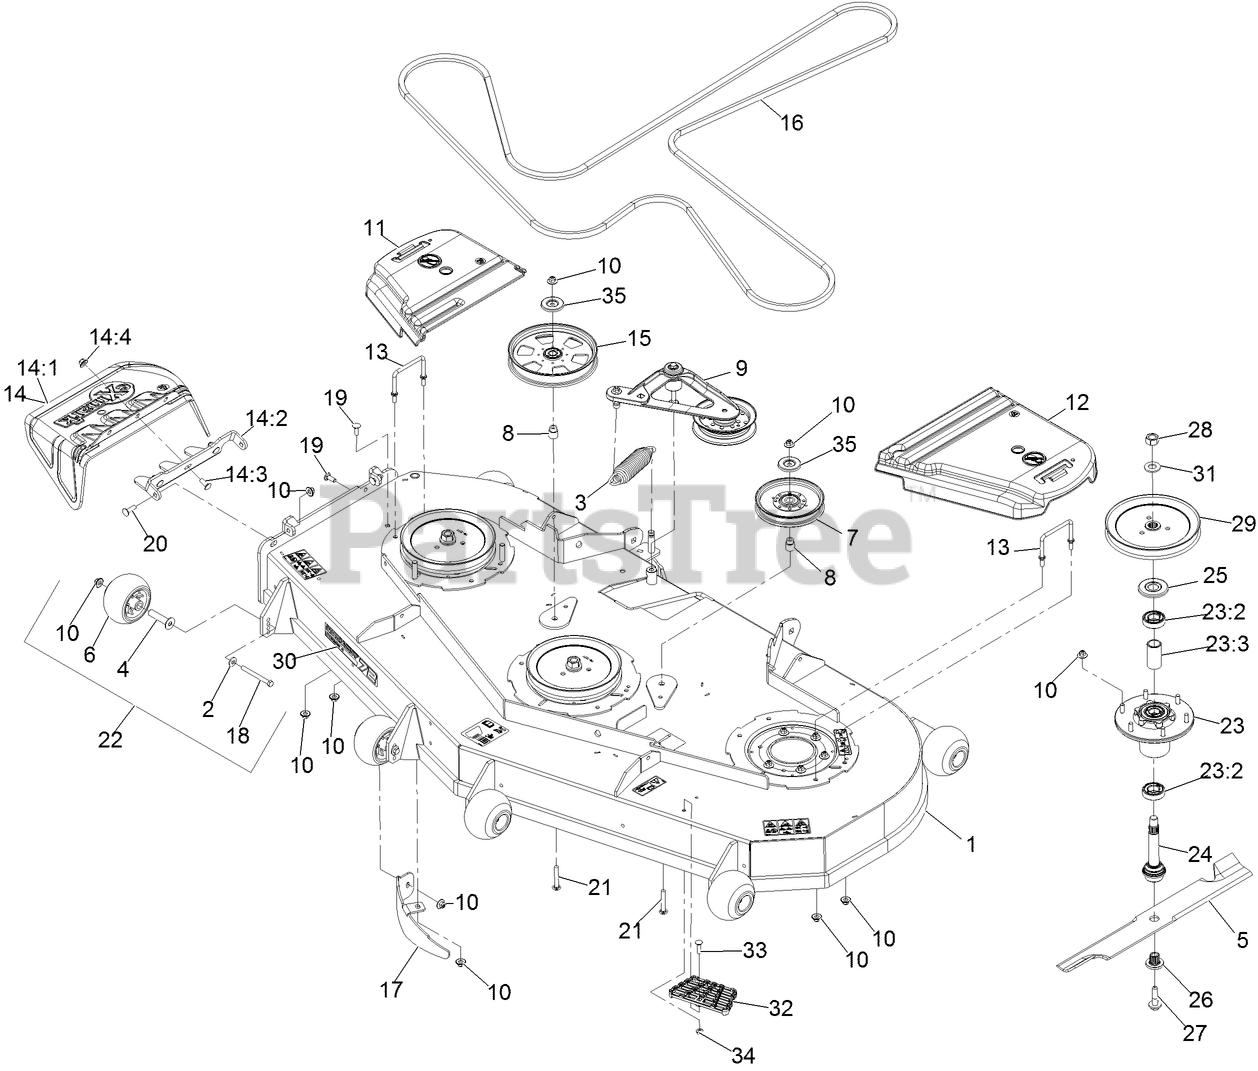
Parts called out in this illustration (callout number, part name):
1	ASM,DECK W/DECALS 724
2	WASHER-BELLEVILLE
3	SPRING-EXTENSION
4	AXLE, ROLLER
6	ROLLER-SCALP, ANTI
7	IDLER-PULLEY
8	BUSHING-IDLER
9	DECK IDLER ASM
10	Nut-Nyloc 3/8-16 Flg
11	COVER-BELT, RH
12	COVER-BELT, LH
13	WIREFORM-COVER
14	ASM,DISCHARGE CHUTE
14:1	CHUTE,DISCHARGE
14:2	BRACKET,DISCHARGE CHUTE
14:3	SCREW-CARR
14:4	Nut-Nyloc 3/8-16 Flg
15	PULLEY-IDLER, FLAT
17	BAFFLE-DOGLEG, LZ72
18	SCREW-HH 3/8-16 X 3 3/4 GR 8
19	SCREW-CARR
20	Bolt-Carriage 3/8-16 X 1 1/4
21	SCREW-CARR
22	KIT, ANTI-SCALP ROLLER
23	ASM-CUTTER HSG WITH BEARINGS
23:2	BEARING-BALL
23:3	SPACER-BEARING
24	ASM-SPINDLE AND SEAL
25	GUARD,BEARING TOP .989
26	BUSHING,SPLINED
27	SCREW,SEMS 1/2-20 X 2.19
28	NUT-HEX
29	SHEAVE,BLADE DRIVE 8.74
30	DECAL, 724
32	STEP-DECK
33	Bolt-Carriage 5/16-18 X 1 1/4
34	NUT-HF, NI
35	SHIELD-DUST
